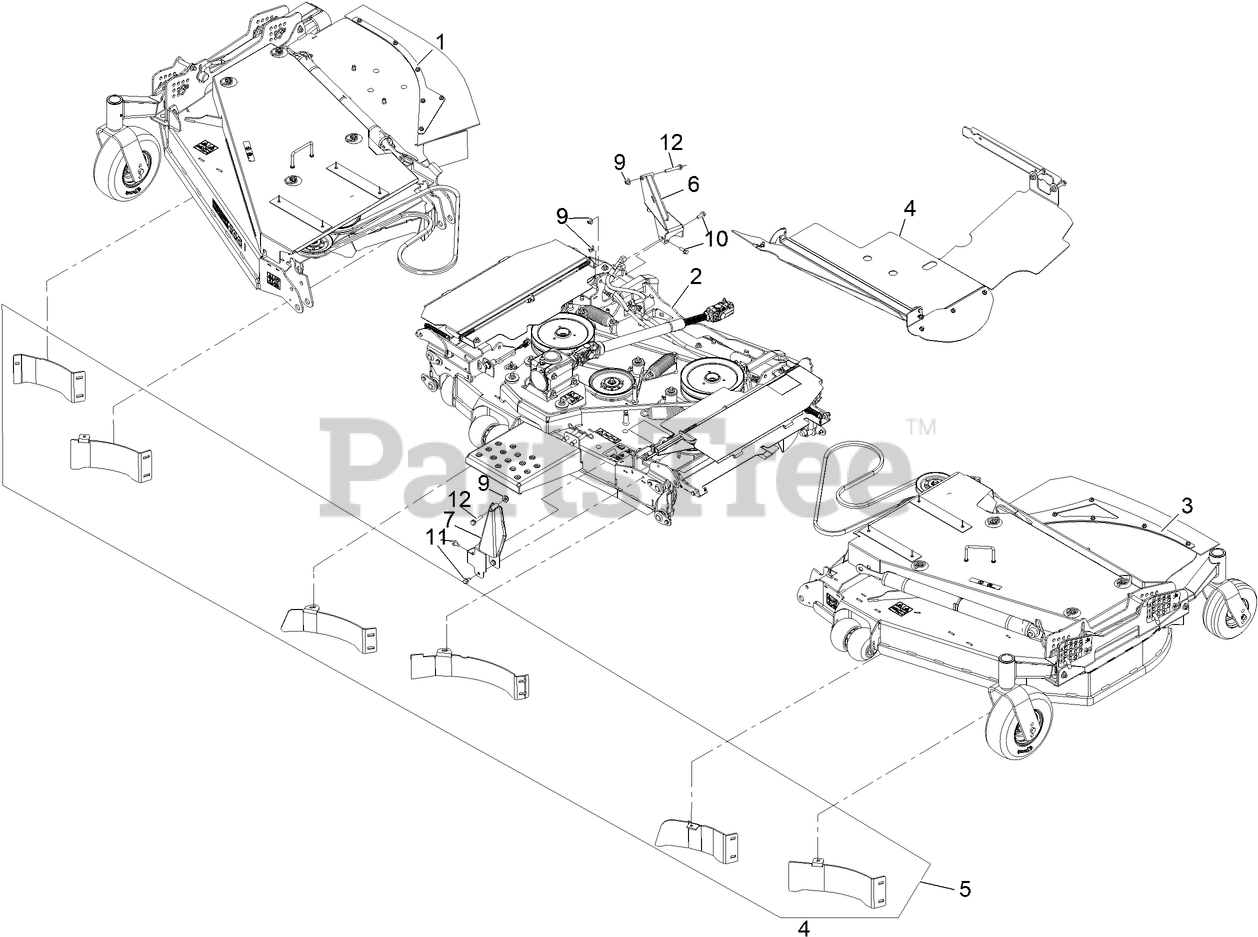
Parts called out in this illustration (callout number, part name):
1	ASM-Deck Wing RH 144 Exmark
2	ASM-Deck-Center, ASM
2	ASM-Deck Ctr 144 Exmark
3	ASM-Deck Wing LH 144 Exmark
5	KIT-FINISH CUT BAFFLE 144
6	Weld-RH Spring Mount-Upstop
7	Bracket, LH Centerdeck-Spring [bl
9	Nut-Nyloc 3/8-16 Flg
10	SCREW-HHF 3/8-16 X 1
11	SCREW-HWH
12	Screw-HHF
